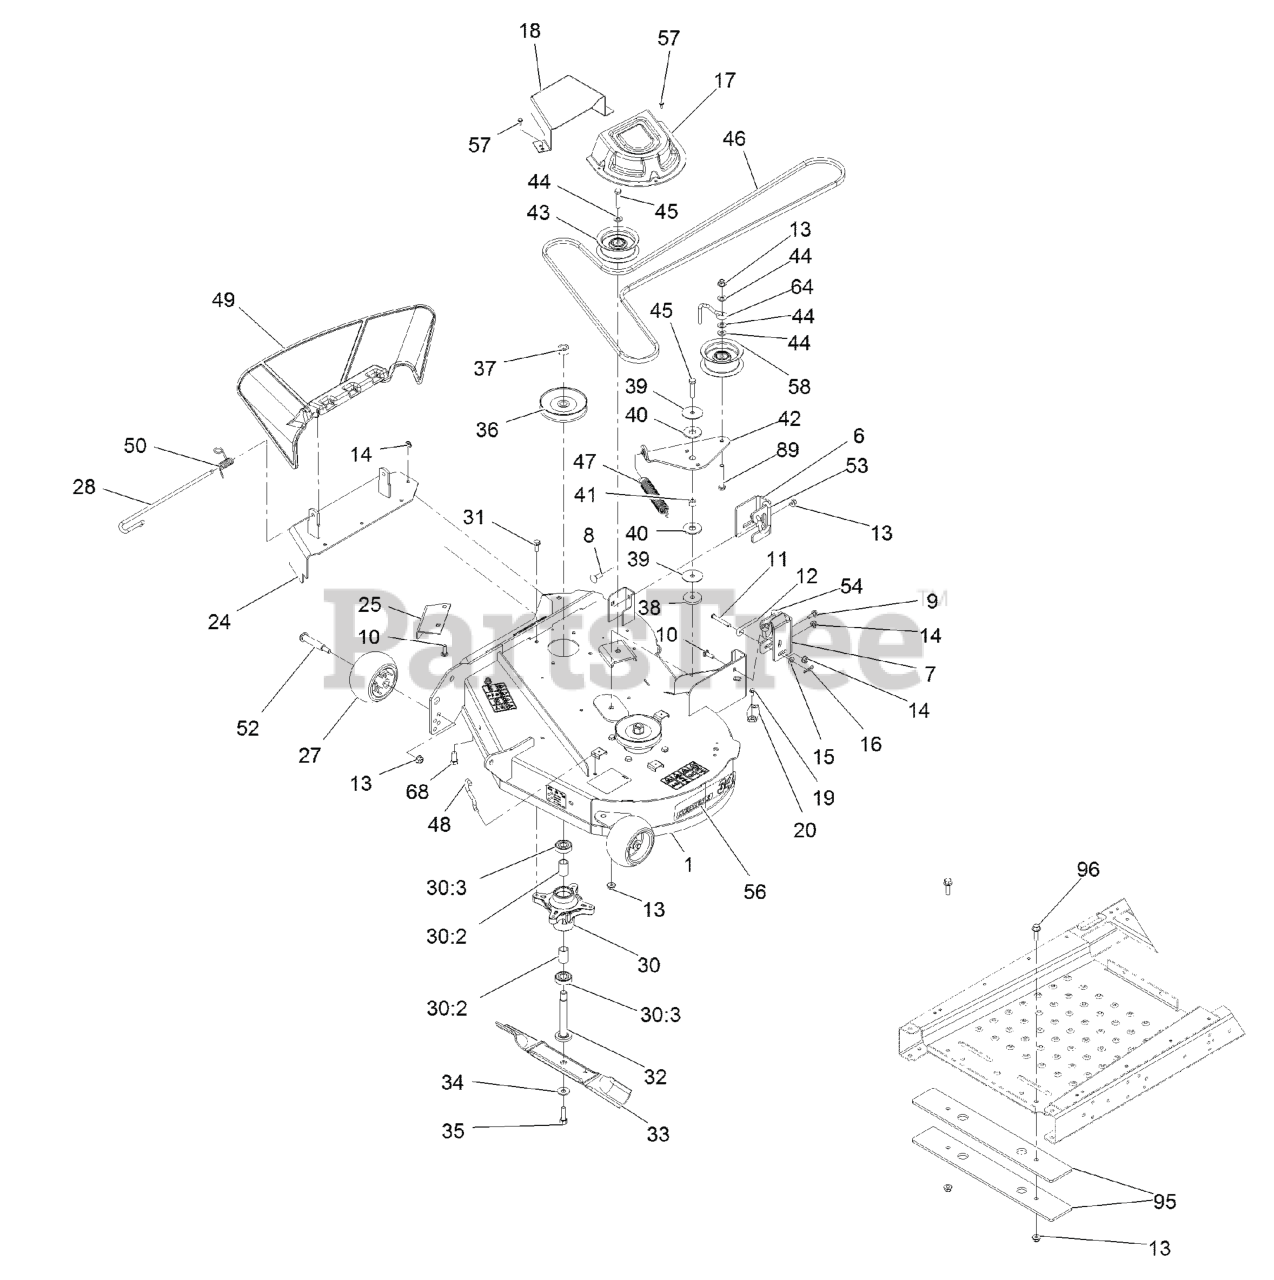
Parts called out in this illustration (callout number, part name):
1	DECK-34 W/DECALS
6	BRACKET-HANGER, RH
7	BRACKET-HANGER, LH
8	BOLT-CARR
9	SCREW-SHOULDER,HWH
10	SCREW-CARR
11	PIN-CLEVIS
12	ROD-LEVEL, DECK
13	NUT-HF, NI
14	NUT-HF, NI
15	WASHER-PLAIN
16	PIN-COTTER
17	COVER-BELT
18	COVER-DECK BELT
19	SCREW-HWH
20	COVER-WASHOUT PORT
24	COVER-DISCHARGE W/DECAL
25	BAFFLE-CUTOFF
27	ROLLER-SCALP, ANTI
28	PIN-CHUTE
30	SPINDLE ASM
30:3	BEARING-BALL
31	SCREW-TAPTITE
32	SHAFT-SPINDLE
33	BLADE-HI LIFT
34	WASHER-BELLEVILLE
35	SCREW-HH
36	PULLEY ASM
37	NUT-HEX
38	WASHER-PLAIN
40	WASHER-FRICTION, COMPOSIT
42	ARM-IDLER
43	PULLEY-IDLER, FLAT
44	WASHER-FLAT
45	SCREW-HH
46	BELT-V
47	SPRING-EXTENSION
48	HOOK-RETURN, SPRING
49	DEFLECTOR-DISCHARGE
50	SPRING-TORSION
52	BOLT-SHOULDER
53	LINK-RETENTION, DECK (RH)
54	LINK-RETENTION, DECK (LH)
56	Decal - Series 2 34
57	SCREW-TAPTITE
58	PULLEY-IDLER,FLAT
64	Belt Guide - Idler
68	SCREW-HH
89	SCREW-HH
95	PLATE-WEIGHT
96	SCREW-HHF
